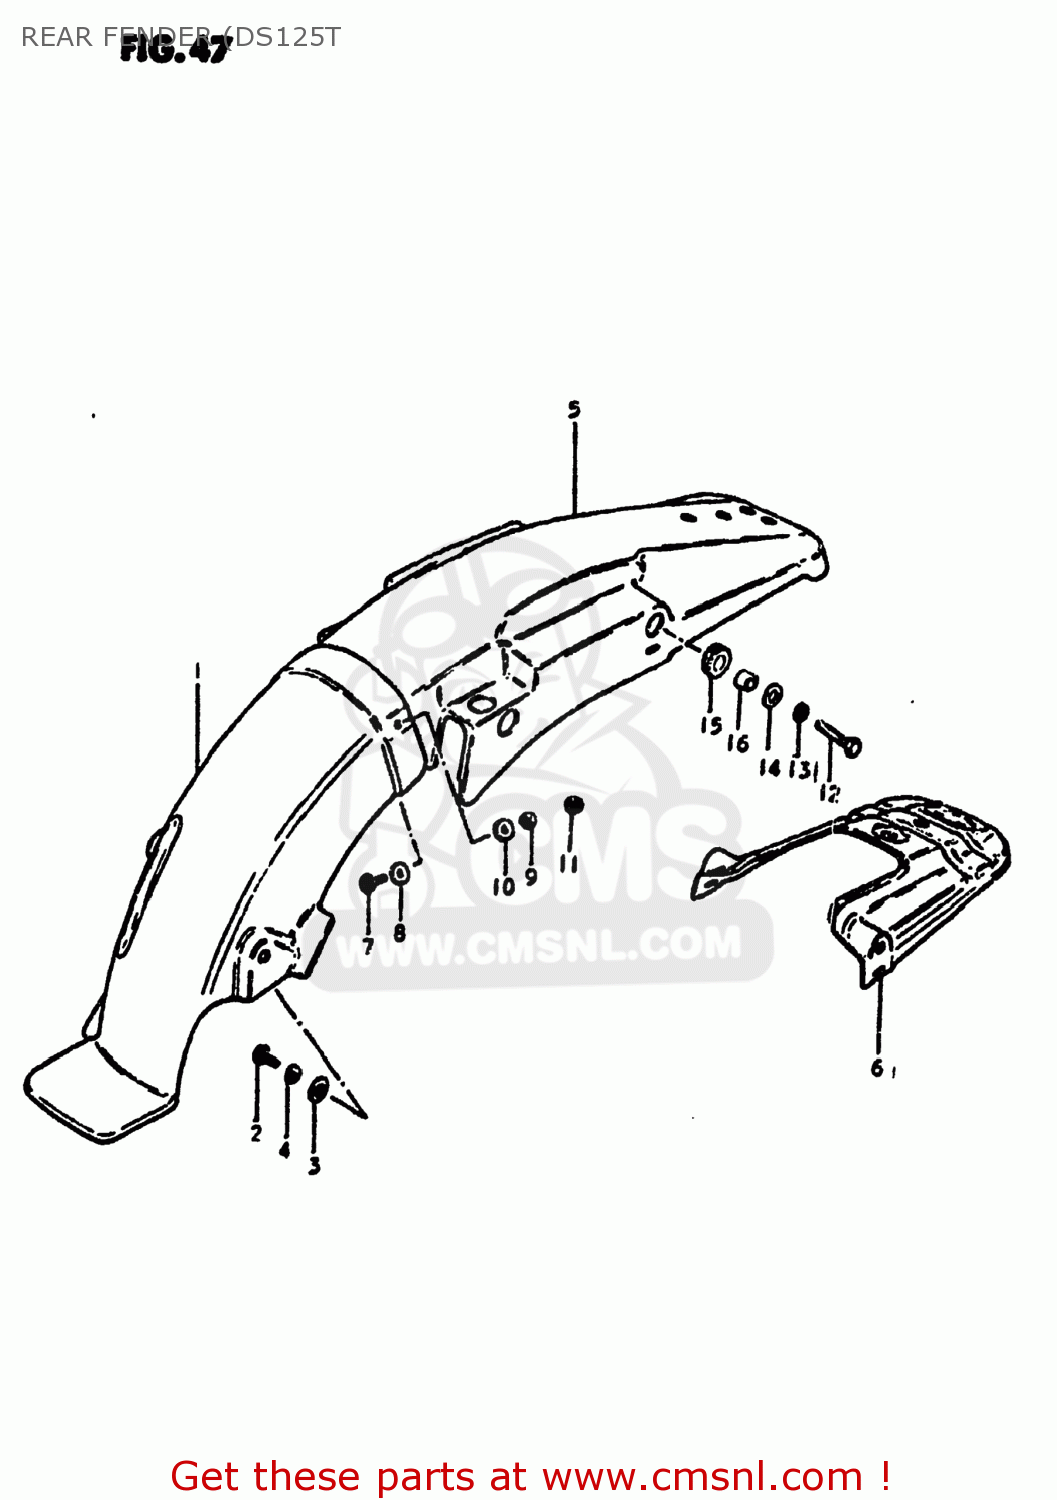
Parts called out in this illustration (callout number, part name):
1	BODY,REAR FENDER,FRONT
2	BOLT, UPPER
3	WASHER
4	LOCK WASHER
5	FENDER,REAR
6	REINFORCEMENT,RR FENDER
7	BOLT
8	WASHER (5.5X16X1.2)
9	LOCK WASHER
10	WASHER(5.2X16X1)
11	NUT
12	BOLT
13	LOCK WASHER
14	WASHER
15	CUSHION
16	SPACER (8.2X12X7.5)
